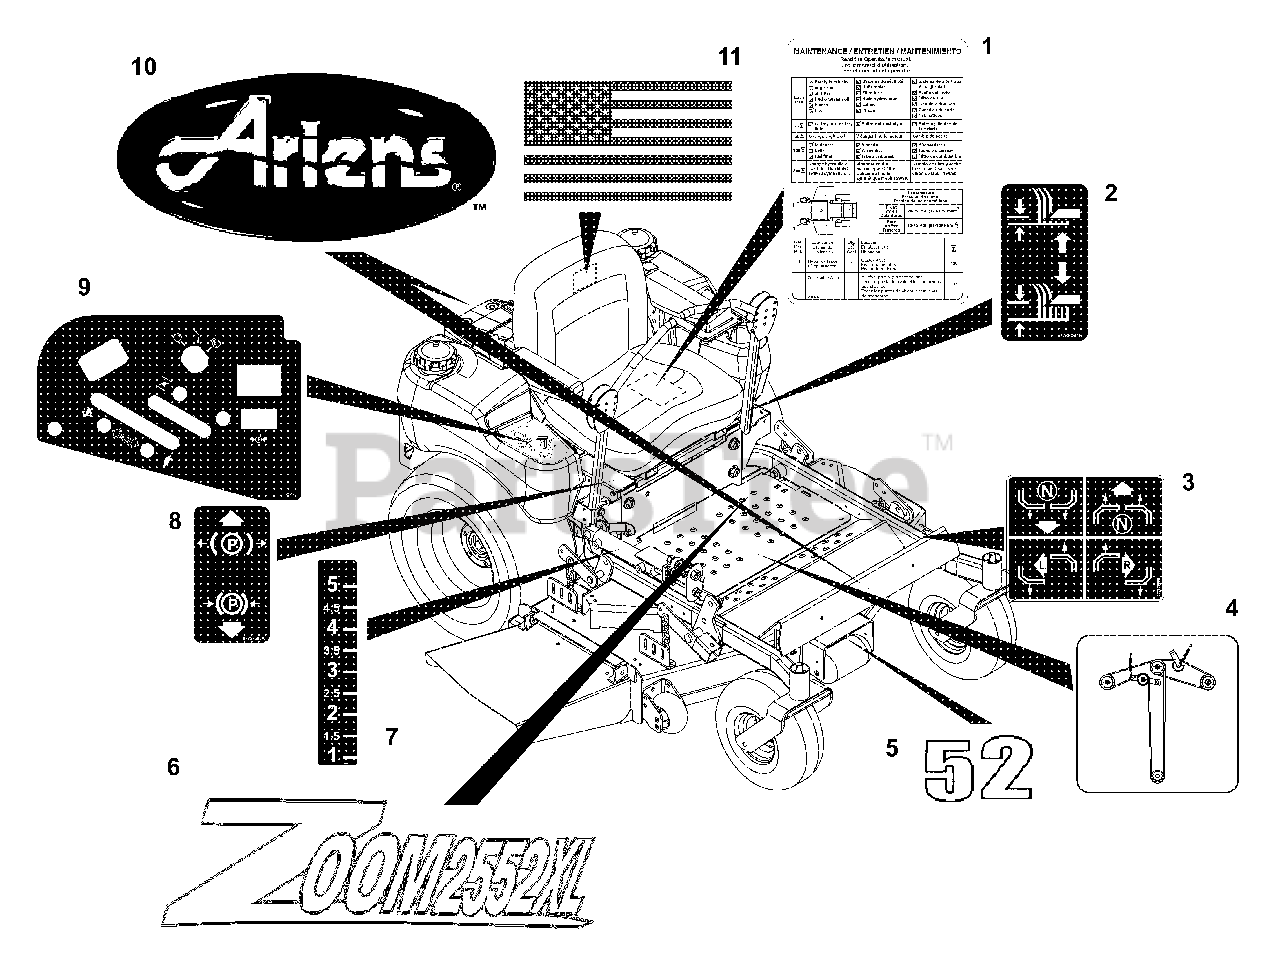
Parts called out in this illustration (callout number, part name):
1	DECAL, MAINTENANCE INSTRUCTION
2	DECAL- LIFT LEVER
3	DECAL, INSTRUCTIONAL-STEERING
4	DECAL, GRAVELY BELT DIAGRAM
5	DECAL - 52"
6	DECAL, ZOOM 2552 XL
7	DECAL, HEIGHT OF CUT
8	DECAL, PARKING BRAKE LEVER
9	DECAL CONTROL PANEL
10	DECAL, ARIENS JEWEL
11	DECAL, AMERICAN FLAG
